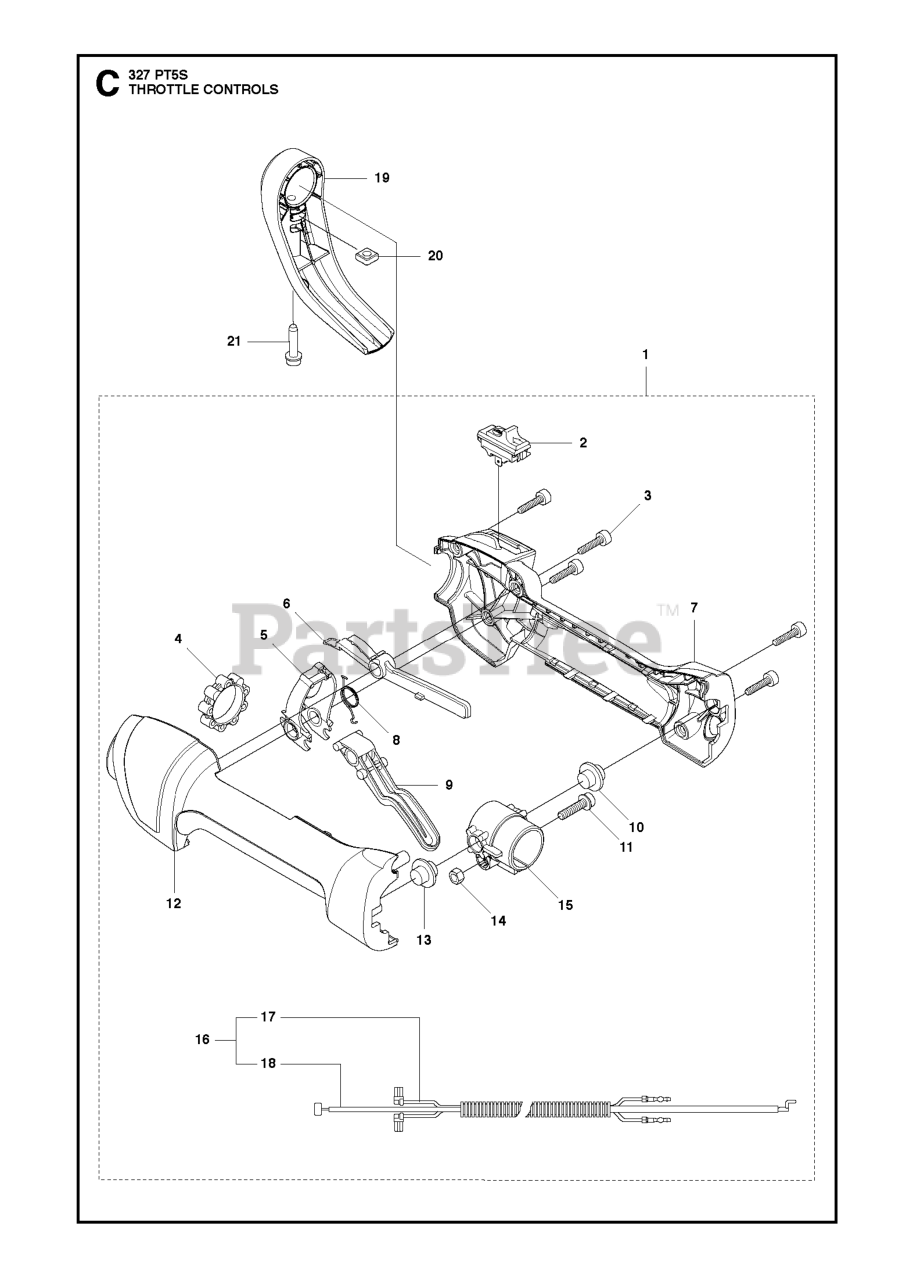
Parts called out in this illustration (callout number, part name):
1	ASSY THROTTLE CONTROL
2	STOP BUTTON
4	VIBRATION DAMPER
6	THROTTLE LOCK
8	RETURN SPRING
9	THROTTLE TRIGGER
10	VIBRATION ABSORBER
13	VIBRATION ABSORBER
17	SHORT CIRCUIT CABLE
18	THROTTLE WIRE ASSY
19	TRIGGER
20	SQUARE NUT M5
21	SCREW ITXSCFM M5X23 10.9 ZN/F
